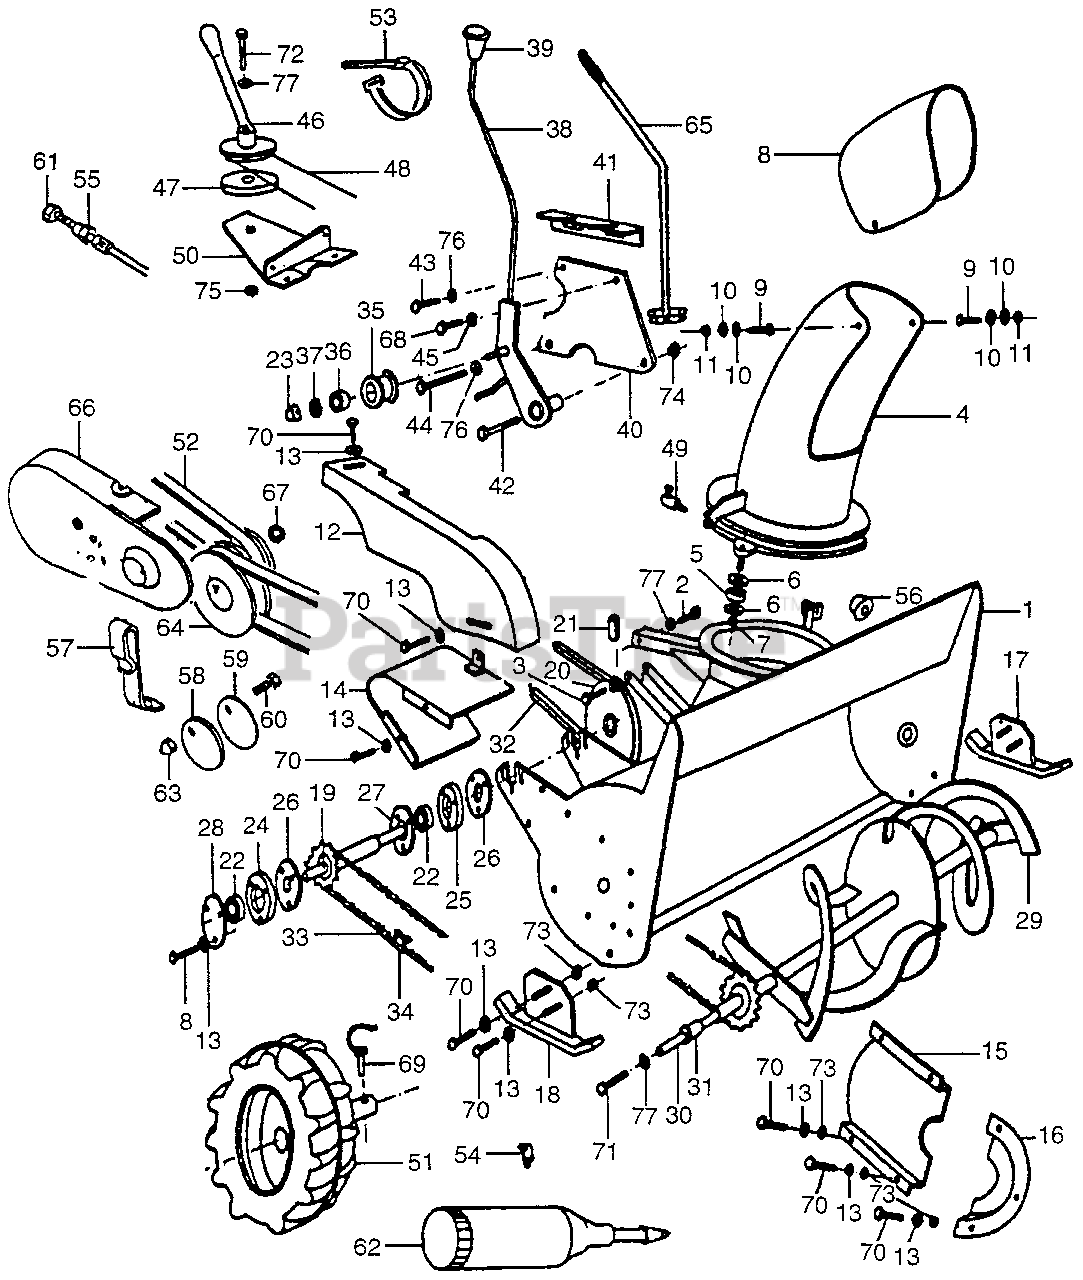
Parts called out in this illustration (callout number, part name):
1	HOUSING, BLOWER Use up to Frame SN 0000290.
1	HOUSING, BLOWER
1	HOUSING, BLOWER Use from Frame SN 0000942.
2	BOLT, TOP FRAME Use up to Frame SN 0000290.
2	BOLT, TOP FRAME Use from Frame SN 0000291.
3	BOLT, FRAME (LOWER)
4	CHUTE (LOWER)
5	SPACER, RUBBER
6	WASHER, CHUTE
7	LOCKNUT (6MM)
8	ROTATING CHUTE TOP Use up to Frame SN 0000941.
8	ROTATING CHUTE TOP
9	BOLT, PIVOT
10	WASHER, PIVOT
11	LOCKNUT (8MM)
12	BELT, GUARD
13	WASHER, EXT. LK (NOT AVAILABLE)
14	GUARD, CHAIN (OUT)
15	GUARD, CHAIN
16	GUARD, SPROCKET
17	PLATE, L. SKID Use up to Frame SN 0000941.
17	PLATE, L. SKID Use from Frame SN 0000942.
18	PLATE, R. SKID Use up to Frame SN 0000941.
18	PLATE, R. SKID Use from Frame SN 0000942.
19	SHAFT, SPROCKET
20	DRIVEN PULLEY
21	ROLLER PIN (6X30)
22	BEARING (6003)
23	RETAINER, PUSH ON
24	HOUSING (OUTER)
25	HOUSING (INNER)
26	RETAINER, BEARING
27	BEARING CAP, IN.
28	BEARING CAP (OUTER)
29	BLADE, WELDMENT
30	BLADE, SPIRAL
31	BUSHING, FLANGE
32	V-BELT (945MM)
33	CHAIN, DRIVE
34	HOUSING (INNER)
35	TENSIONER, IDLER Use up to Frame SN 0000290.
35	TENSIONER, IDLER Use from Frame SN 0000291.
36	BEARING (608/2Z)
37	CIRCLIP (22MM)
38	SHAFT, TENSIONER Use up to Frame SN 0000941.
38	SHAFT, TENSIONER Use from Frame SN 0000942.
40	PLATE, BASE
41	LEVER, LOCK Use up to Frame SN 0000290.
41	LEVER, LOCK Use from Frame SN 0000291.
42	BOLT, PIVOT
43	BOLT, HEX. (6X15MM)
44	SPACER, BOLT
45	PLATE, SPACER
46	HANDLE, CONTROL
47	WASHER, NYLON
48	CABLE, CHUTE
49	LOCK, CABLE
50	BASE, CONTROL
51	WHEEL ASSY.
52	V-BELT (663MM)
53	COLLAR, CABLE
54	FITTING, GREASE
55	CUP, CABLE HOUSING
56	CUP, CABLE HOUSING
57	HOOK, WIRE
58	ADJUSTER, CAM CHAIN
59	ADJUSTER, CHAIN
60	BOLT (8MM)
61	NUT, CABLE ADJUSTING
62	GREASE GUN
63	NUT, ADJUSTER
64	PULLEY, DRIVE
65	LEVER, CHANGE
66	COVER, BELT *PB1*
67	WASHER, DISTANCE
68	BOLT, HEX. (5X20)
69	CLIP, PIN (31MM)
70	BOLT, HEX. (6X10)
71	BOLT, HEX. (10X25) Use up to Frame SN 0000290.
72	BOLT, HEX. (10X50)
73	NUT, HEX. (6MM)
74	NUT, HEX. (8MM) Use up to Frame SN 0000290.
74	NUT, HEX. (8MM) Use from Frame SN 0000291.
75	NUT, HEX. (10MM)
76	WASHER, PLAIN (6MM)
77	WASHER, SPRING (8MM) Use up to Frame SN 0000290.
77	WASHER, SPRING (8MM) Use from Frame SN 0000291.
